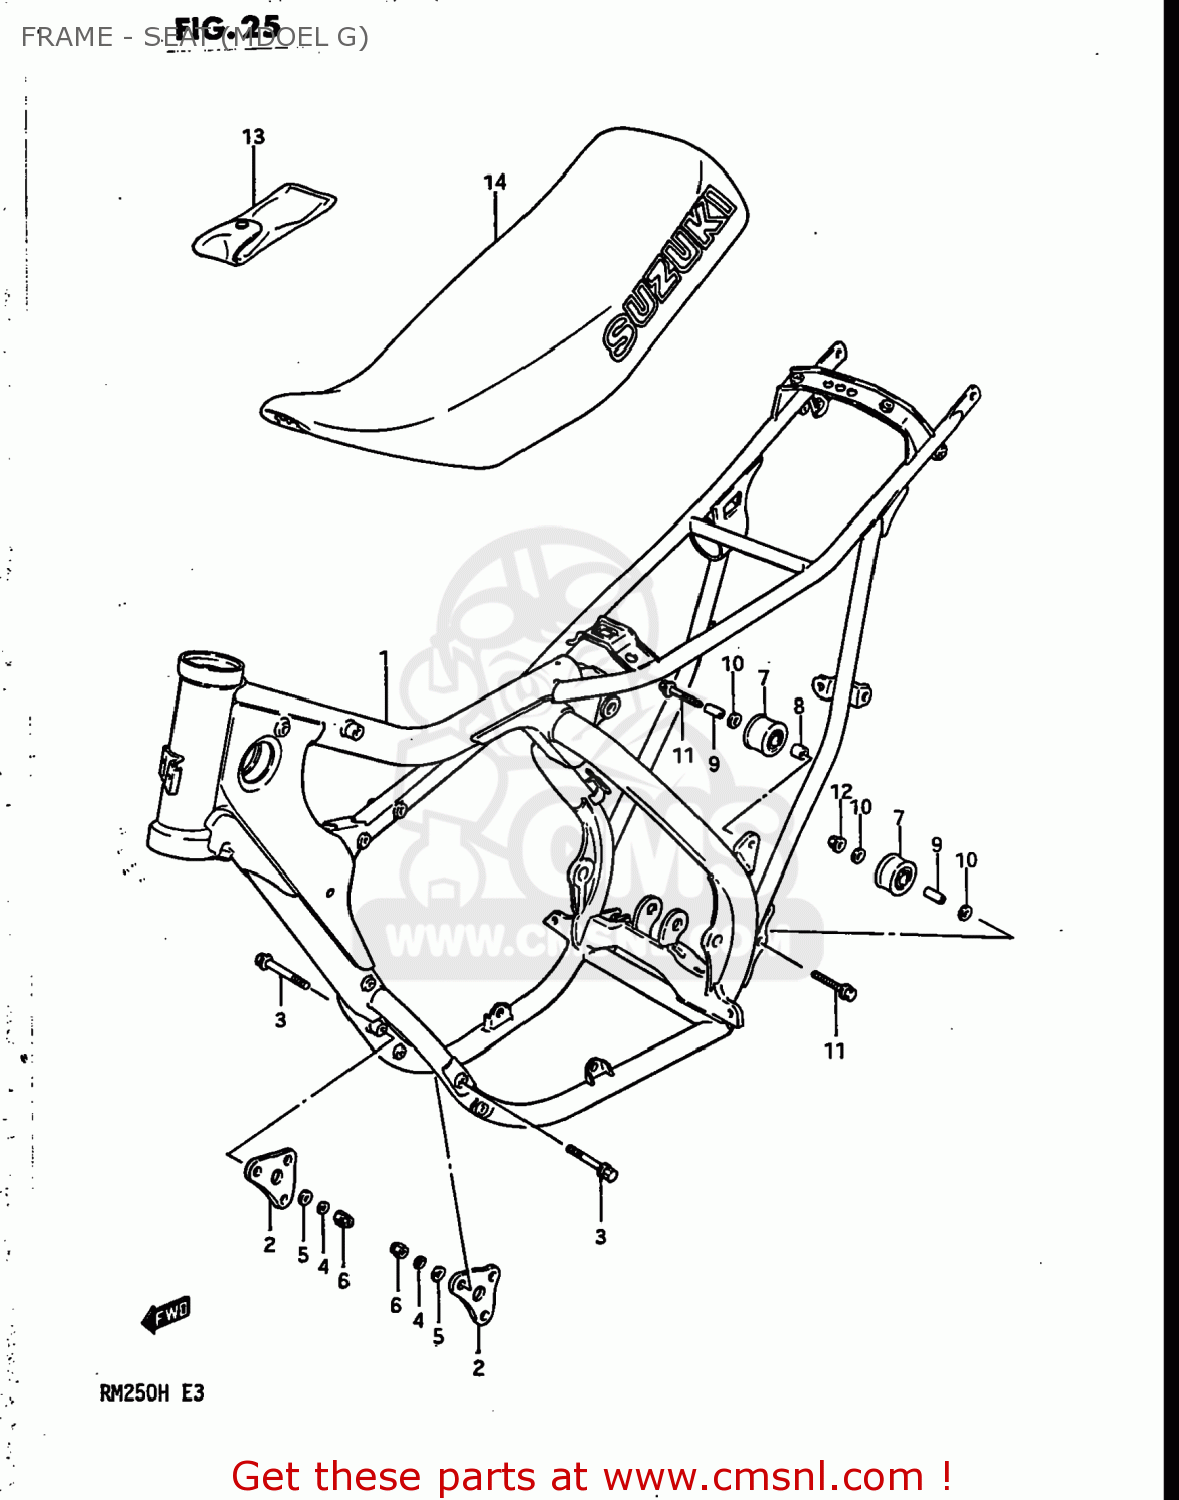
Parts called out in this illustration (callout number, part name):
1	FRAME
2	PLATE,ENGINE MOUNTING
3	BOLT 8X55
4	LOCK WASHER
5	WASHER
6	NUT
7	ROLLER,CHAIN CONTROL
8	SPACER (8.5X15X10)
9	SPACER(8.6X12X25.5)
10	WASHER
11	BOLT(8X45)
12	NUT
13	TOOL SET
14	SEAT ASSEMBLY
